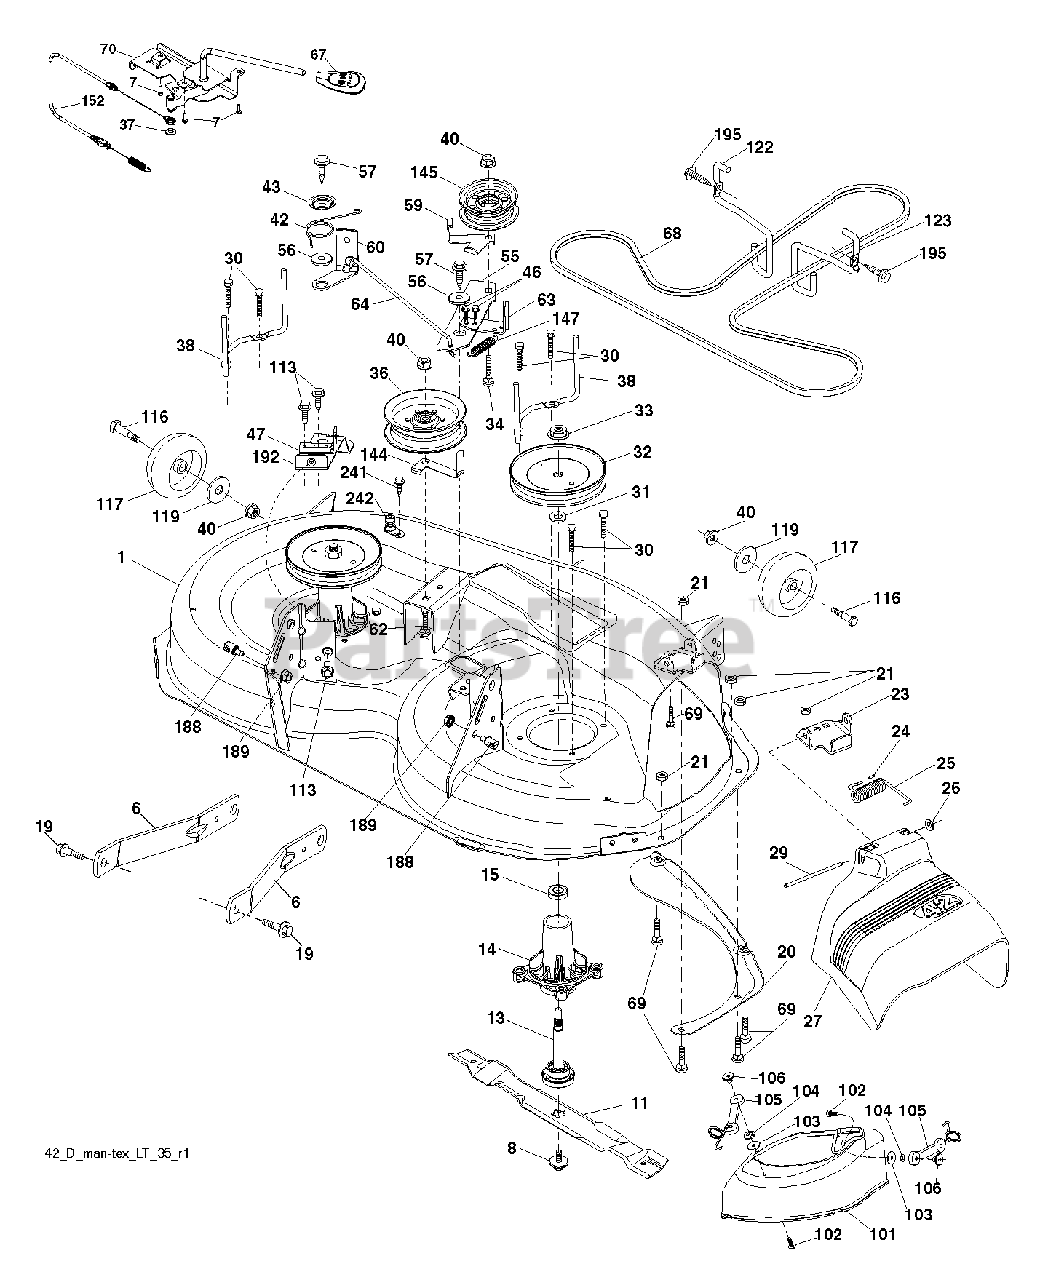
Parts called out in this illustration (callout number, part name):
1	DECK SVC 42" 2GWB 419175X668
6	ARM.SUSPENSION.MOWER.R
7	SCREW.#10 X 0.750.BOS
8	BOLT.WASHER.ASM.7/16-2
11	42" HI-LIFT BLADE
13	SHAFT.ASM.MDRL.N/GREASE.38
14	HOUSING.MANDREL.4PT.
19	BOLT.SHOULDER
20	BAFFLE.VORTEX
21	LOCKNUT
23	BRKT.DEFLECTOR.38"2005+
24	CAP-SLEEVE LT
25	SPRING.TORSION.DEFLECT
26	NUT PUSH M
27	SHIELD.DEFLECTOR.MOWER.42"BLAC
29	ROD.HINGE
30	SCREW, WASHER HEAD
31	WASHER.SPACER.MANDREL
32	PULLEY.MANDREL.5.438.PD
33	NUT.FLANGE.LOCK.TOP
34	BOLT.3/8-16X1.50
36	PULLEY.IDLER.2006
37	WASHER
38	KEEPER.BELT.MANDREL.PULLEY
40	NUT LOCK FLG 3/8-16 UNC
42	SPRING.TORSION.BRAKE
43	SRPING.TORSION.RETAINE
46	SCREW.1/4-20X5/8
47	BRKT.CLUTCH.CABLE
55	IDLER.ARM.42"
56	SPACER.RETAINER
57	SCREW 3/8-16X1
59	GUARD, BELT
60	ARM BRAKE MOWER
63	ARM BRAKE MOWER
64	LINKAGE.BRAKE.ASM.ZINC
67	HANDLE.CLUTCH.CABLE.LT
68	BELT.DECK.DRIVE.42"
69	BOLT
70	CLUTCH.ASM.MANUAL.YT.PREDATORQ
102	SCREW
104	LOCKWASHER (3 2)
105	LATCH ASSY
106	WELDNUT
113	BOLT.5/16HEX.WHS.HD
116	BOLT.SHOULDER.3/8-16X3-5/8.
117	WHEEL. GUAGE RALLY
119	WASHER
122	KEEPER BELT ENGINE LH
123	KEEPER BELT RH
144	KEEPER.BELT.MOWER
145	PULLEY.IDLER.48"PRIMARY
147	RETURN SPRING
152	CABLE.CLUTCH.CABLE.W/SPRING
188	STUD.FASTNER.W/ANTI-ROTATE
189	NUT LOCK HEX FLANGE 5/16-18
192	BRKT.BRAKE.STAND.LH.
195	SCREW, 3/8-16X3/4
241	SCREW.TT.#10-32X.5.3/8.FLANGE
242	PORT.WASHOUT
